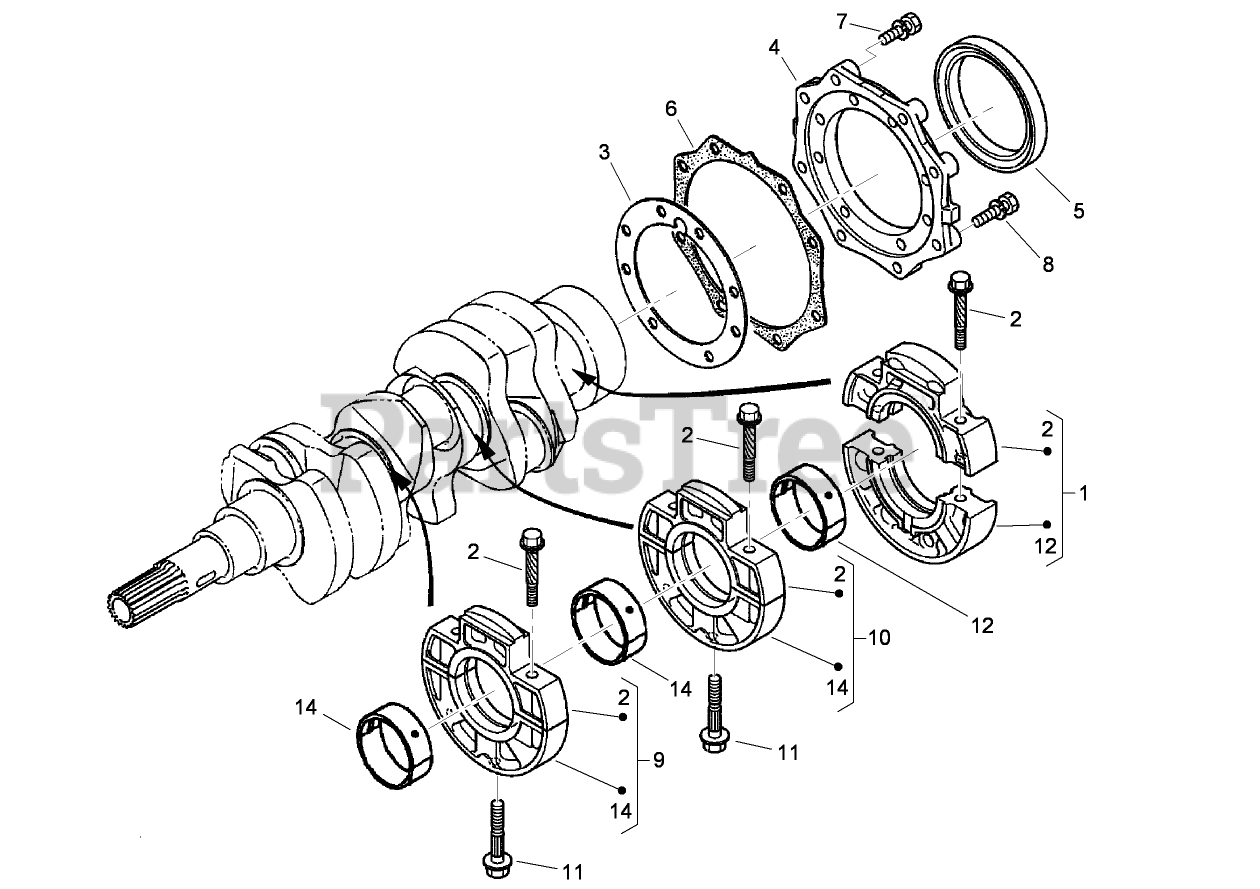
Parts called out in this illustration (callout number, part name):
1	WHEEL CASE BEARING ASM
2	BOLT-CASE, BEARING
3	GASKET-CASE, BEARING
4	COVER-CASE, BEARING
5	SEAL-OIL
6	GASKET-COVER, CASE
9	MAIN CASE BEARING ASM
10	MAIN CASE BEARING ASM
11	BOLT-CASE, BEARING
12	CRANKSHAFT METAL ASM (STD)
12	CRANKSHAFT METAL ASM (-0.20MM)
12	CRANKSHAFT METAL ASM (-0.40MM)
14	CRANKSHAFT METAL ASM (STD)
14	CRANKSHAFT METAL ASM (-0.20MM)
14	CRANKSHAFT METAL ASM (-0.40mm)
